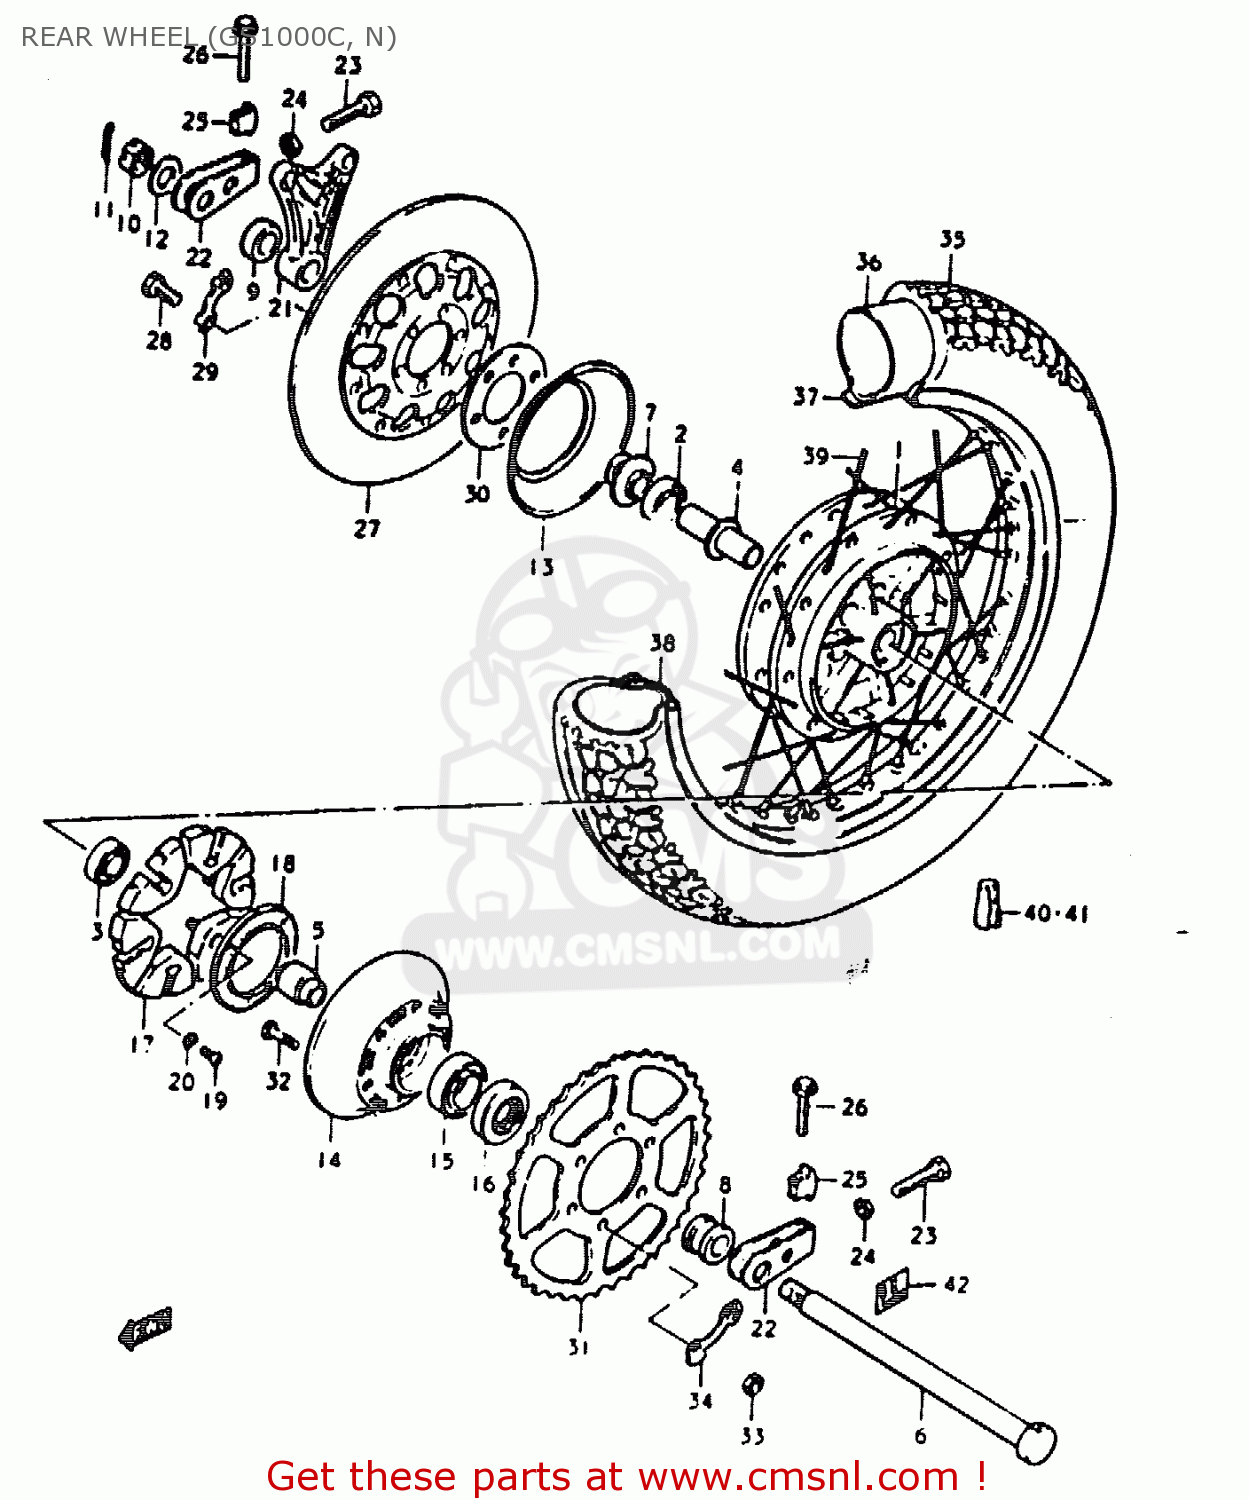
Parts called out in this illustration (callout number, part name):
1	DRUM,REAR HUB
2	BEARING
3	BEARING, LH
4	SPACER,REAR HUB BEARING
5	SPACER,REAR HUB BEARING
6	AXLE,REAR
7	SPACER,REAR AXLE,RIGHT
8	SPACER(20X33X28.3)
9	SPACER(20X38X12)
10	NUT 18MM
11	PIN,COTTER
12	WASHER(19X34X4)
13	COVER,REAR WHEEL HUB
14	DRUM,REAR SPROCKET MOUNT
15	BEARING
16	SEAL,OIL(33X62X7)
17	ABSORBER,REAR HUB SHOCK
18	PLATE,REAR HUB SHOCK ABSORBER
19	SCREW
20	LOCK WASHER
21	BRACKET,REAR CALIPER
22	ADJUSTER,CHAIN
23	BOLT
24	NUT
25	SUPPORTER,CHAIN ADJUST
26	BOLT (8X40)
27	DISC,BRAKE
28	BOLT 8X40
29	WASHER
30	SHIM,BRAKE DISC
31	SPROCKET,REAR
32	BOLT
33	NUT
34	WASHER
35	TIRE
36	TUBE ASSEMBLY,WHEEL,INNER
37	PROTECTOR,INNER TUBE
38	RIM (N17X7T2.50)
39	SPOKE SET
40	BALANCER,WHEEL (B)
41	BALANCER,WHEEL (30G)
42	LABEL,CHAIN WEAR INDICATOR
